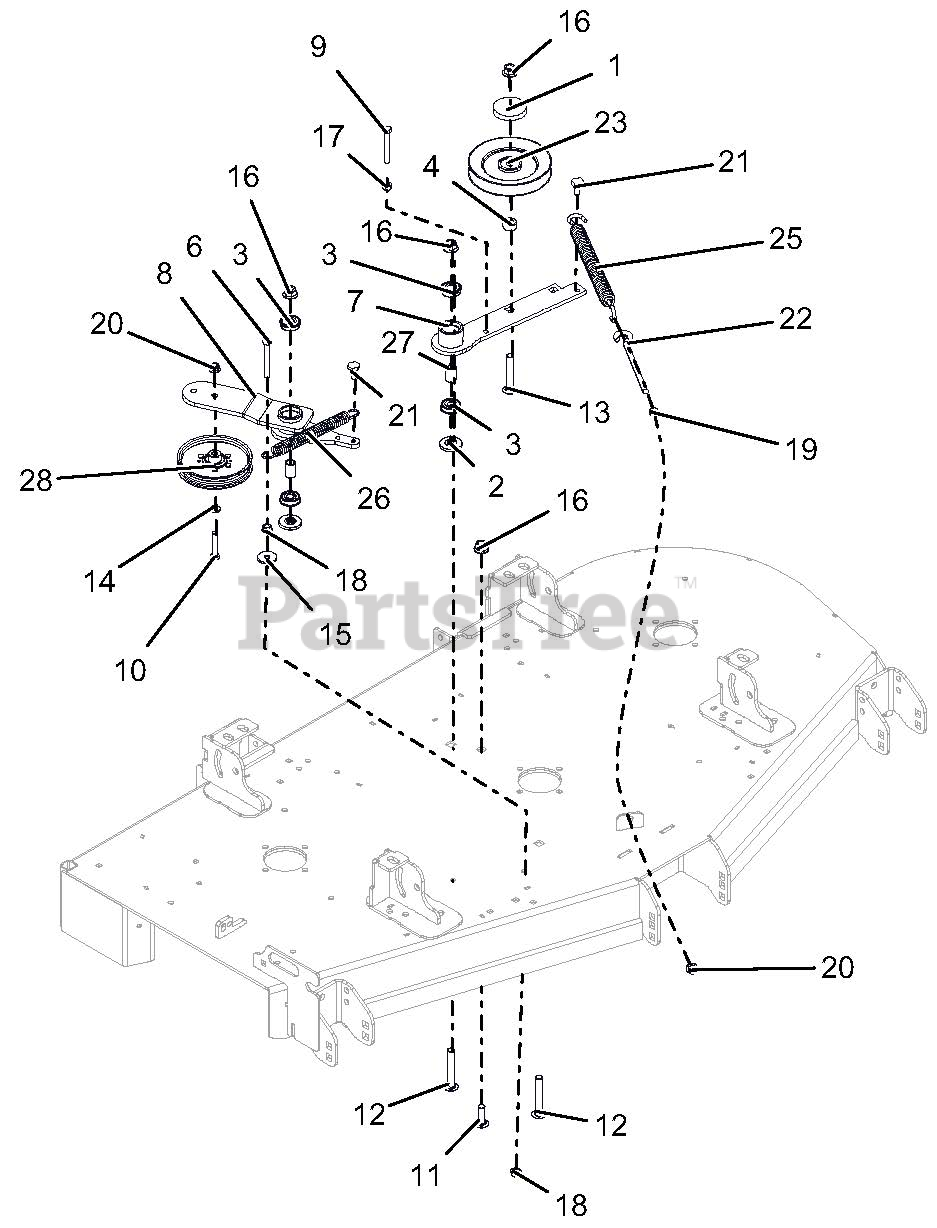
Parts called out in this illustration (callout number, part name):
1	CAP, IDLER BEARING SEALING
2	SPACER, IDLER ARM
3	BRG, BALL .501 X 1.38 X .438 SEALED
4	BSHG, SPCR .502 X .997.50 PM
6	BLT-HEX .38-16X3.00 GR5 YWZC
7	WLDMT, DECK PTO IDLER ARM
8	WLDMT, DECK RH IDLER ARM
9	BLT-HEX .38-16X2.75 GR5 YWZC
10	BLT-HEX .38-16X2.00 GR5 YWZC
11	BLT-RDHDSQSHNK .50-13X1.50 YWZC
12	BLT-RDHDSQSHNK .50-13X3.25 YWZC
13	BLT-RDHDSQNK .50-13X3.00 G5 Y
14	WSHR-FL-STL.406X.812X.065 YWZ
15	WSHR-FL-STL .406X1.375X.135 YZ
16	NUT-LK-NYL-FLG .50-13 YWZC
17	NUT-HEX .38-16 YWZC
18	@NUT-SPNLK-FLG .375-16 YWZC
19	NUT, JAM .375-16 YWZC
20	NUT-LK-NYL-FLG .38-16 YWZC
21	BLT, SHLDR EP .38-16X.30 HEX YZ
22	BOLT, .38-16X6.00 .62 DIA EYE
23	SHEAVE, .50" ID X 6.00" OD V-IDLER
25	SPRG, EXTENSION
26	SPRG, EXTENSION .120X.845X6.55 WLD
27	SPACER, .510 X .750 X 1.148
28	PULLEY, FLAT IDLER .500 X .375 W/BRG
